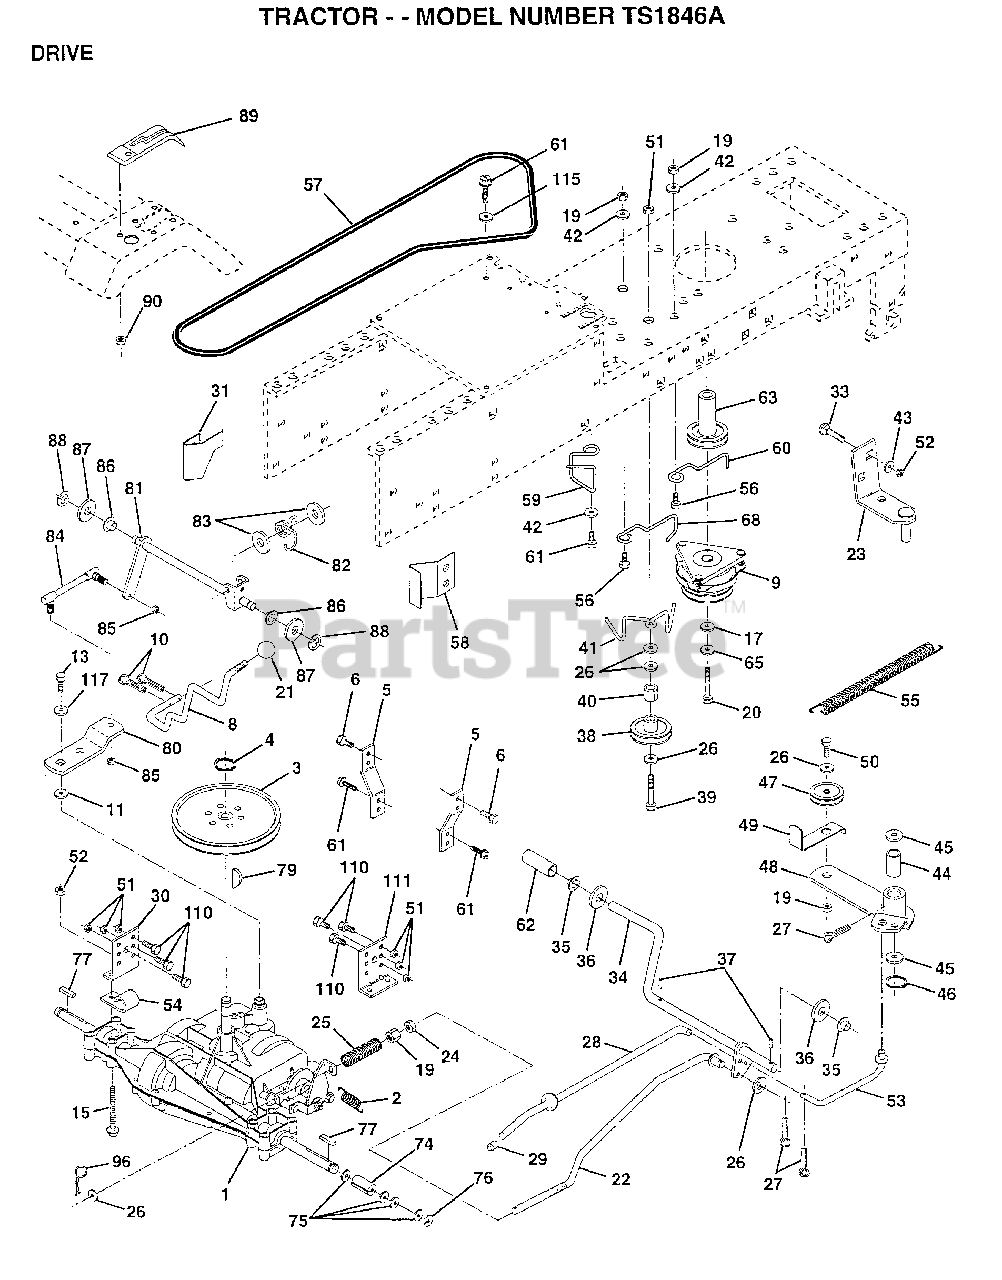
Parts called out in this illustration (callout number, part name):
1	TRANSAX. PRLES.
3	PULLEY TRANSAXLE
4	RING
5	STRAP TORQUE
6	SCREW
10	PIN COTTER 1/8
11	WASH-SHFT PLT LT
13	BOLT.1/4-28.W/PAT
15	BOLT.HX.FLG.5/16
17	WASHER
19	NUT
20	BOLT.7/16-20X4.25
21	KNOB.DUCKHEAD.1/2
22	ROD.ASM.BK.44.MWR
23	BRACKET.ASM.MTG
24	NUT
25	"SPRING,ROD BRAKE"
26	WASHER
27	COTTER PIN
28	ROD.BRAKE.PARK.LT
29	PLUNGER CAP T
30	BRKT TRANS LH
31	KEEPER BELT LH
33	BOLT
34	SHAFT FOOT PEDAL
35	NYLON BEARING
36	WASHER LT
38	PULLEY.IDLER.FLAT
39	BOLT
40	SPACER T
41	KEEPER BELT
42	WASHER
43	WASHER T
44	"LY, BEARING"
45	WASHER LT
46	KLIP RING
48	ARM IDLER
49	RETAIN BELT
53	"LINK, CLUTCH T"
54	"CLIP,INSULATOR"
55	"SPRING, RETURN LT"
57	BELT.GRDRV.94.75
58	"KEEPER,BELT RH"
59	KEEPER BELT CNTSP
60	KEEPER BELT ENGLH
61	SCREW
62	PEDAL COVER T
63	PULLEY ENGINE
65	LOCKWASHER
68	"KEEPER,BLT ENG LT"
74	SPACER HYT
75	WASHER
76	E RING HYT
77	SQ KEY STD
80	"ARM,SHIFT"
81	"SHAFT,SHIFTER"
82	"SPRING,TORSION"
83	WASHER
84	"ROD,TIE "
85	NUT.CNT.LOCK.1/4
86	BUSHING
87	WASHER D
88	KLIP RING
89	CONSOLE SHIFTER
90	NUT
96	RETAINER M
111	BRKT TRANS RH
115	WASHER GT
117	WASHER PM
